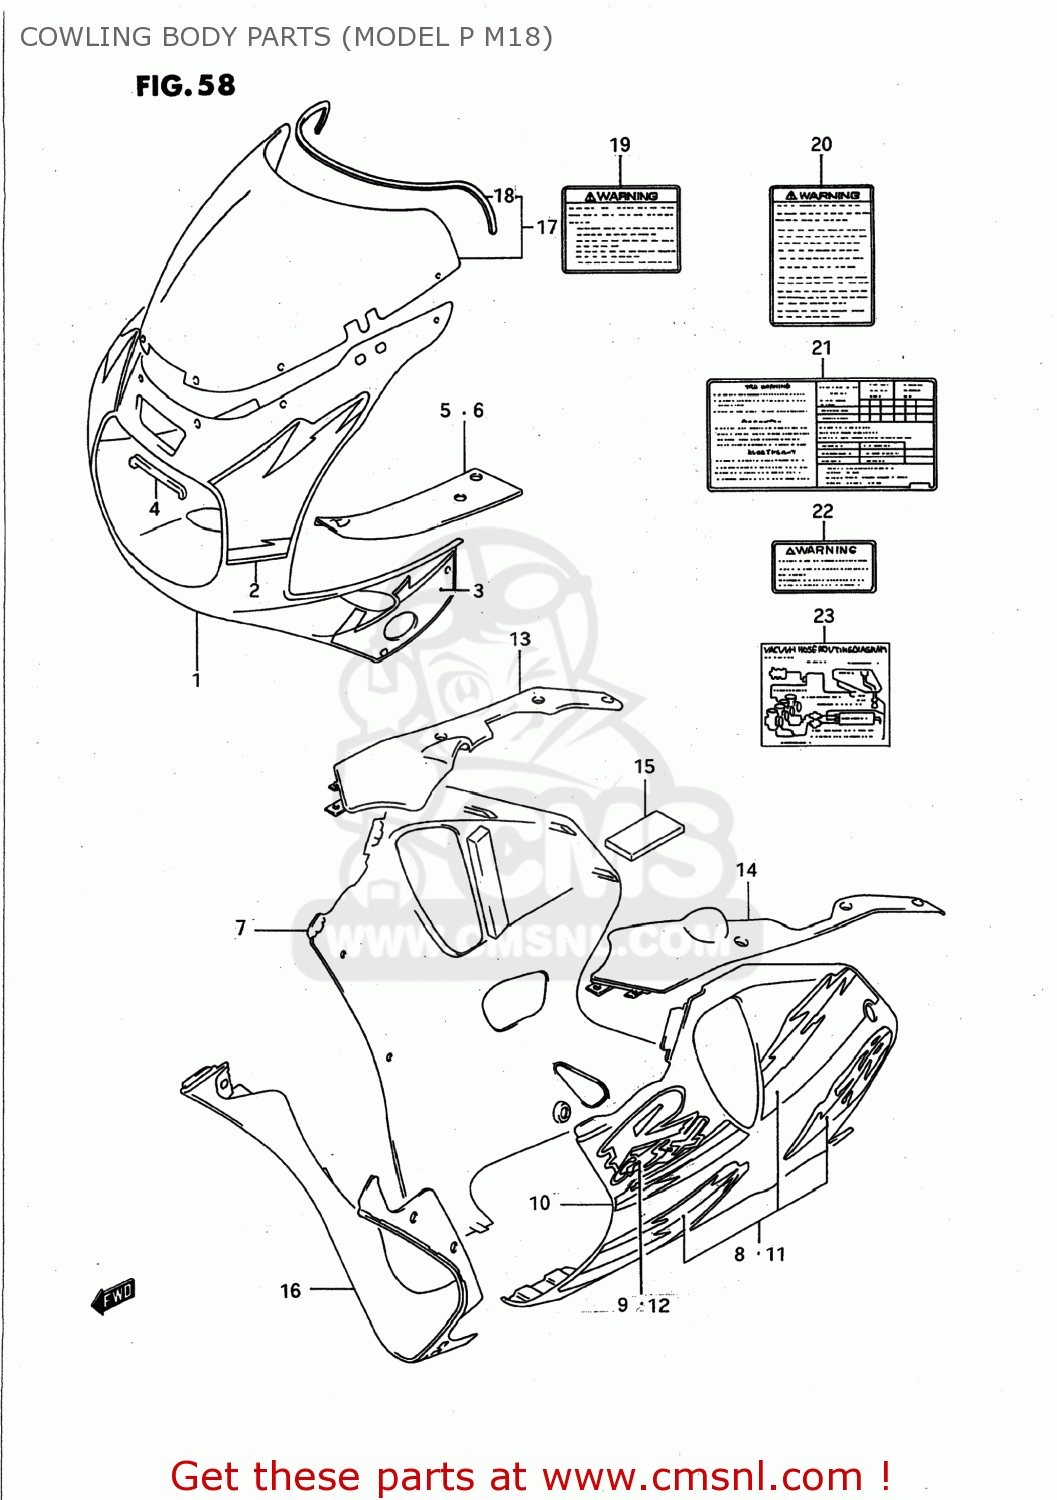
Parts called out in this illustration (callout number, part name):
1	COWLING ASSY,BODY
2	TAPE SET,COWLING BODY,FRONT
3	TAPE SET,COWLING BODY
4	CUSHION,FR POSITION LAMP
5	PANEL,UPR,R
6	PANEL,UPR,L
7	COWLING ASSY,UNDER,R
8	TAPE SET,COWL UNDER,R
9	EMBLEM,COWLING,UNDER
10	COWLING ASSY,UNDER,L
11	TAPE SET,COWLING,UNDER
12	EMBLEM,COWLING,UNDER
13	PANEL,LWR,R
14	PANEL,LWR,L
15	CUSHION,PANEL
16	COWLING,UNDER CTR
17	WINDSCREEN SET
18	MOLDING
19	LABEL
20	LABEL (WARNING SCREEN)
21	LABEL (TIRE AIR PRESSURE)
22	LABEL,WARNING STEERING
23	LABEL (VACUUM HOSE ROUTING)
